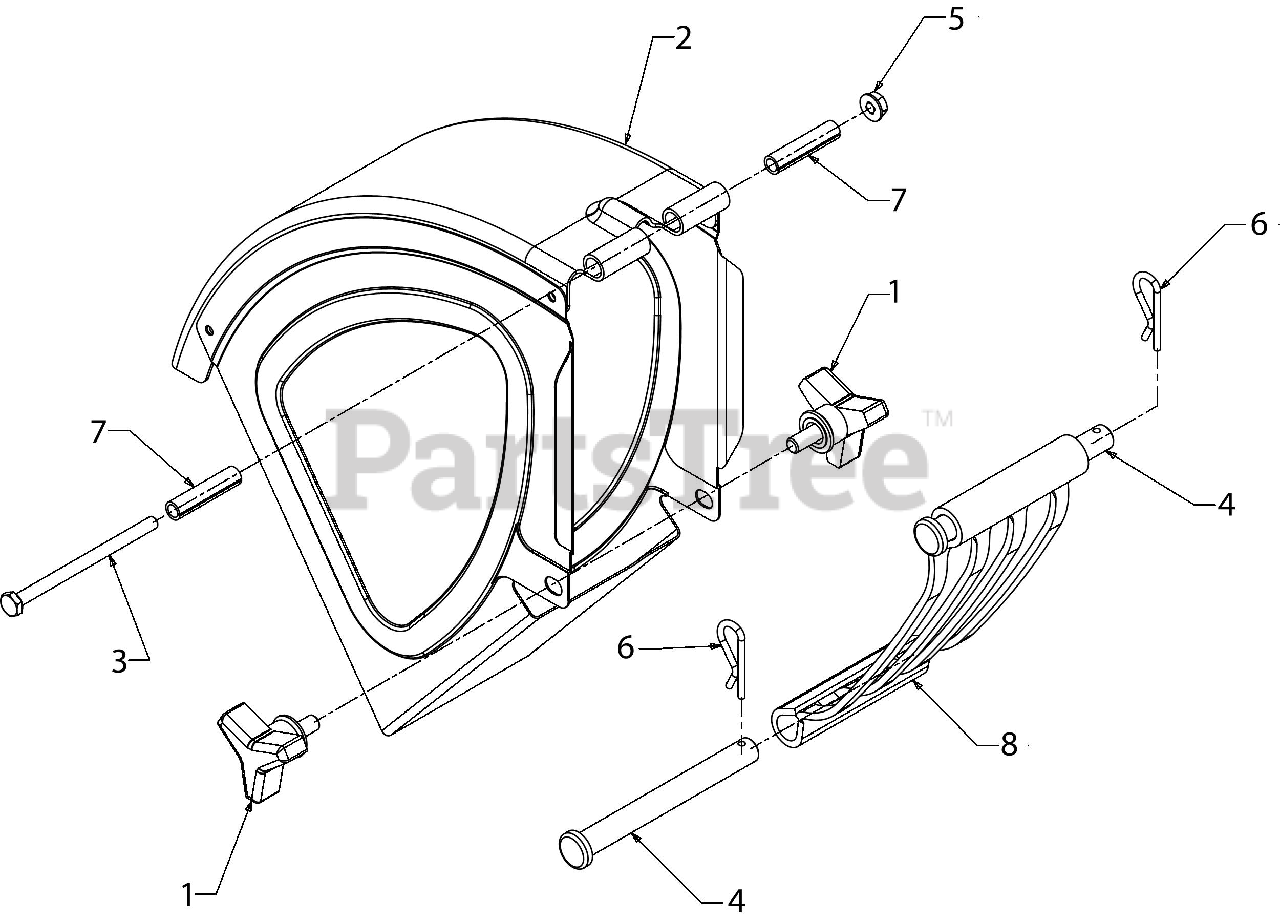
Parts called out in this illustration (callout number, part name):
1	KNOB ASSEMBLY
2	DISCHARGE CHUTE ASSEMBLY
3	SCREW 1/4-20 X3.75 GR5
4	CLEVIS PIN
5	LOCK NUT 1/4
6	COTTER PIN
7	SPACER-.260 x .3
8	SHREDDER SCREEN
